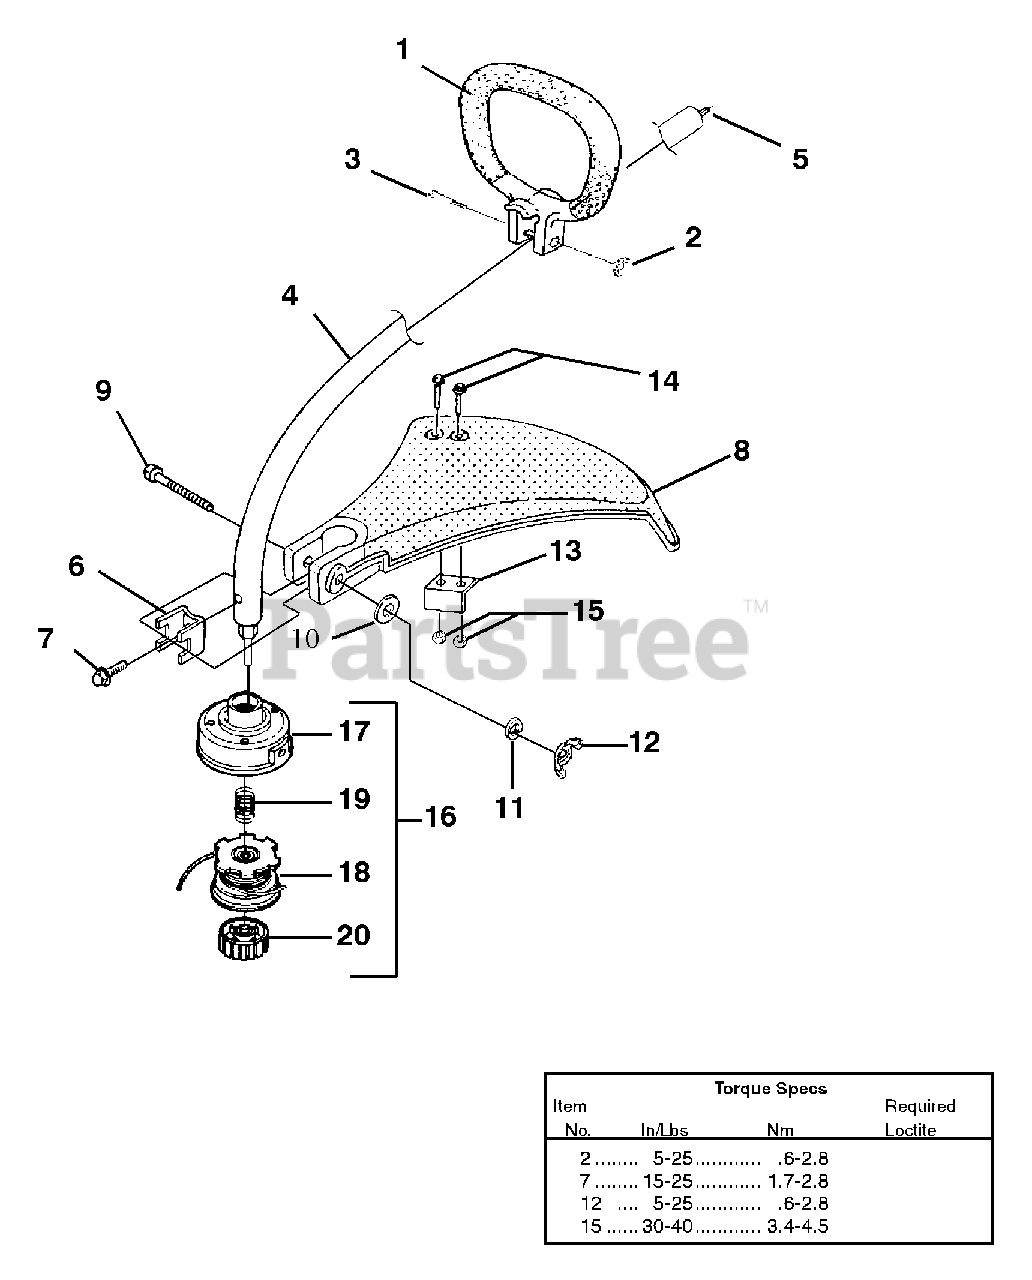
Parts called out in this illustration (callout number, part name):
1	HANDLE ASSY.-Front
2	NUT-Wing, Washer Faced (1/4-20)
3	SCREW-Cap Hex Hd.
4	DRIVESHAFT HOUSING ASSY.
5	SHAFT-Flexible
6	CLAMP
7	SCREW-Sems Hex Hd. (#10-24 X 3/8")
8	DEFLECTOR & BLADE KIT (55 Deg.)
9	SCREW-Cap Hex Hd. (1/4-20 X 2")
10	WASHER-Flat (1/4")
11	WASHER-Lock (1/4")
12	NUT-Wing, Washer Faced (1/4-20)
13	BLADE-Cut-Off
14	SCREW-Mech. Hex Hd. (10-24 X 7/8")
15	NUT-Hex (10-24)
16	STRINGHEAD-Complete
17	HOUSING & EYELET (Dual Line)
18	SPOOL & STRING (.080" Line)
19	SPRING-Compression
20	RETAINER-Spool (R.H. Thread, Black)
